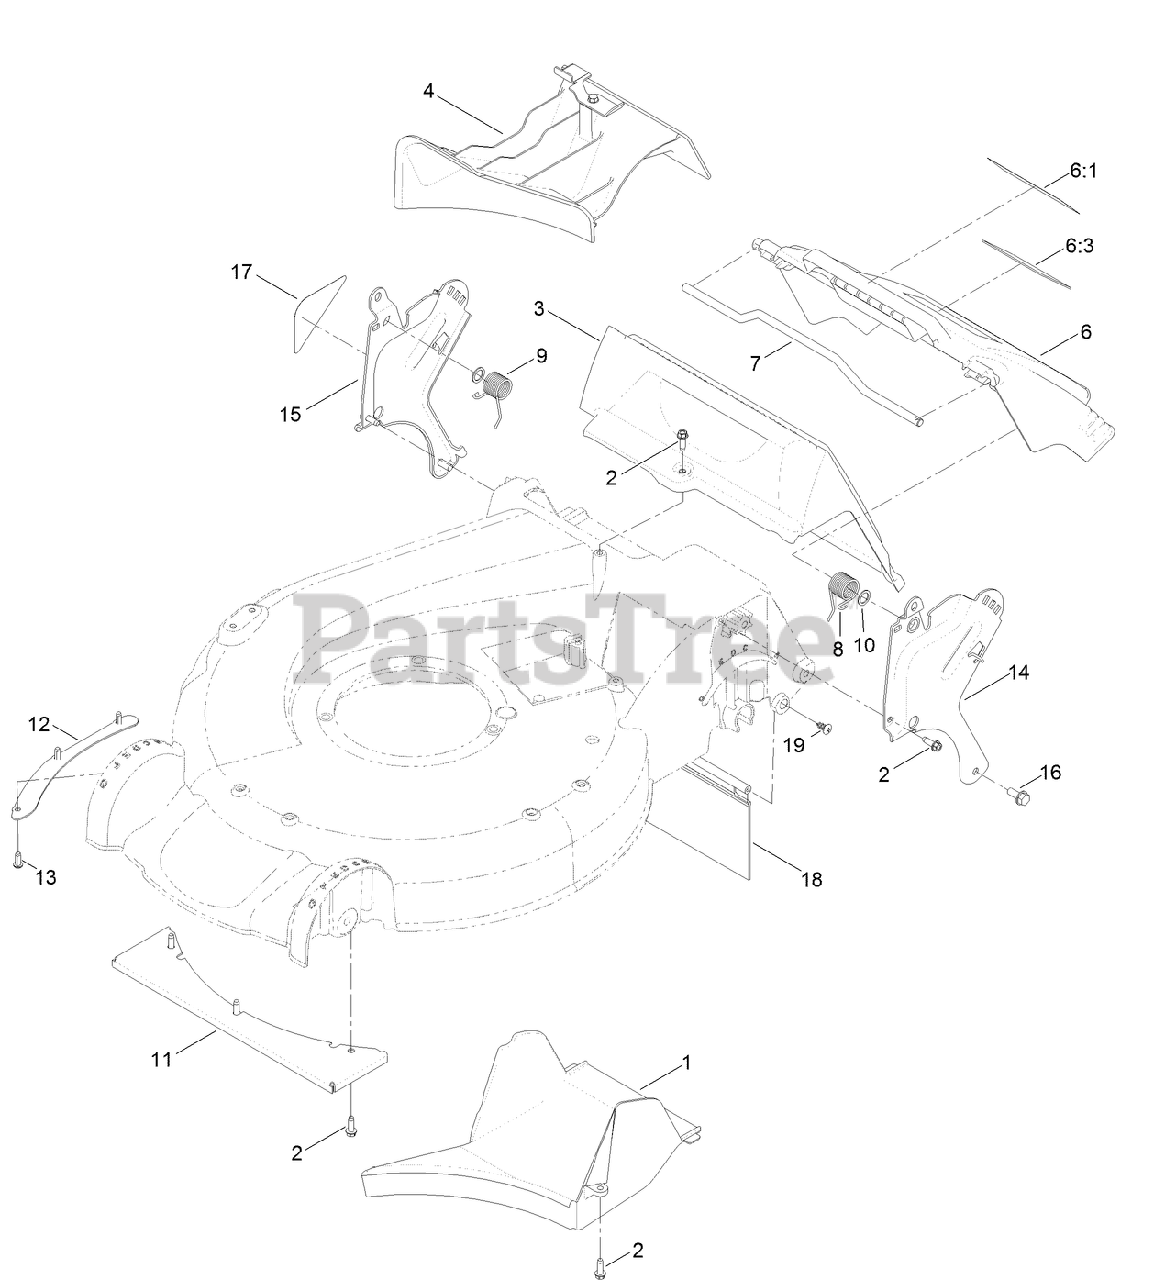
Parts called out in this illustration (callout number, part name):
1	TUNNEL-DISCHARGE
2	SCREW-HWHTF
4	MULCH PLUG ASM
6	REAR DOOR ASM
6:1	DECAL-WARNING
6:3	DECAL-WARNING
7	ROD-DEFLECTOR
8	SPRING-TORSION
9	SPRING-TORSION
10	WASHER-NYLON
11	PLATE-COVER, FRONT
12	SHEET-LIP
13	SCREW
14	BRACKET-HANDLE, LH
15	BRACKET-HANDLE, RH
16	SCREW-THD ROLL, HWH
17	DECAL-INSTRUCTION
18	SHIELD-TRAILING
19	SCREW-PTH
